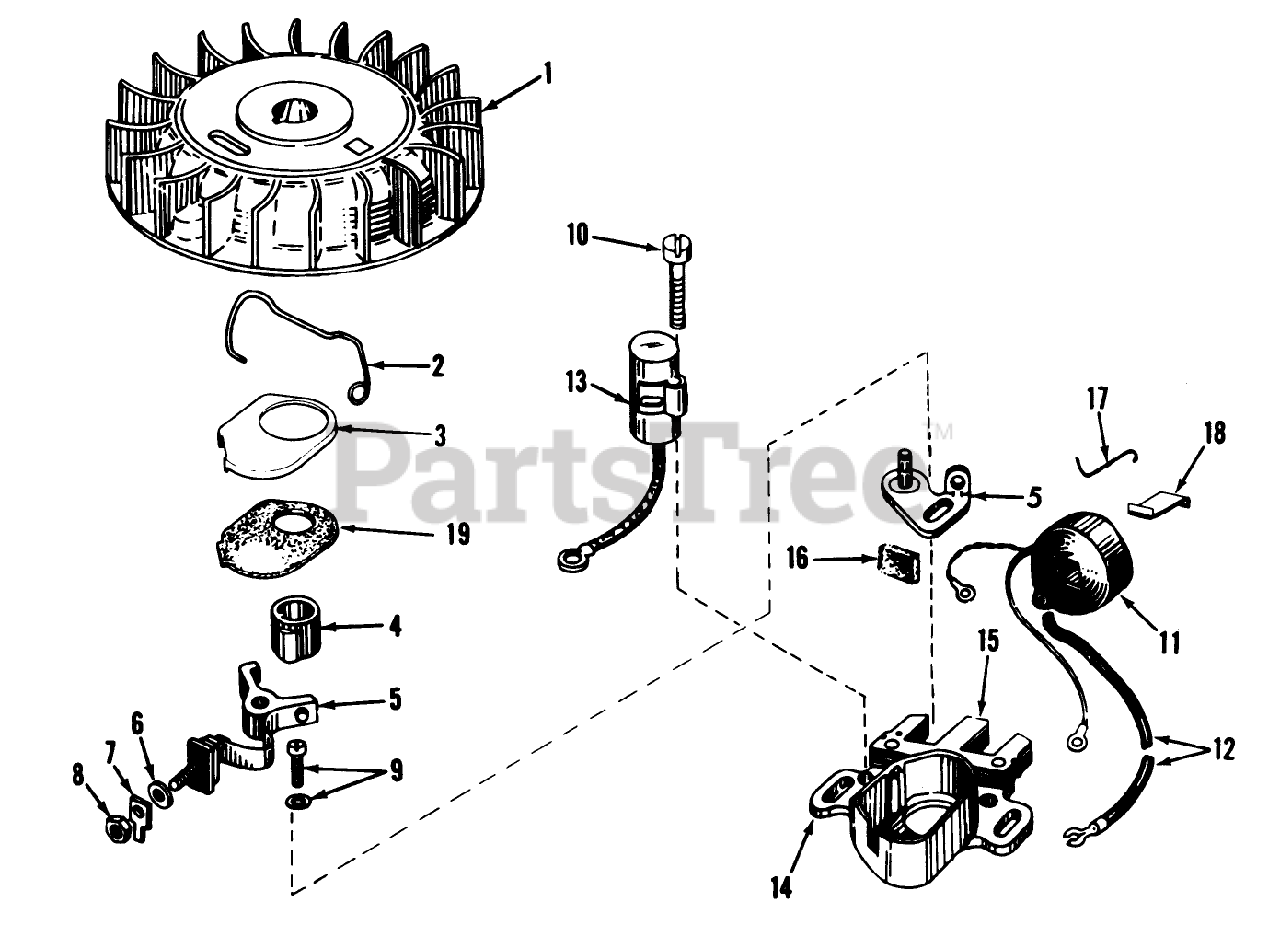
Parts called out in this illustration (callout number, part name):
1	Flywheel
2	Spring Breaker Box
3	Cover-Dust
4	Cam-Breaker
5	Breaker Assy.
6	Washer
7	Terminal, Ground
8	DECAL
9	Breaker Screw
10	Condenser Screw
11	Coil Assy. (Incl. # 12)
12	Wire, Lead
13	Condenser
14	Core & Plate
15	Stator Assy. (Incl. # 2, 3, 5 thru 14 & 16 thru 19)
16	Felt,Cam Wiper
17	Clip, Coil
18	Spring Coil Wedge
19	Gasket-Dust Cover
19	Gasket, Dust Cover
